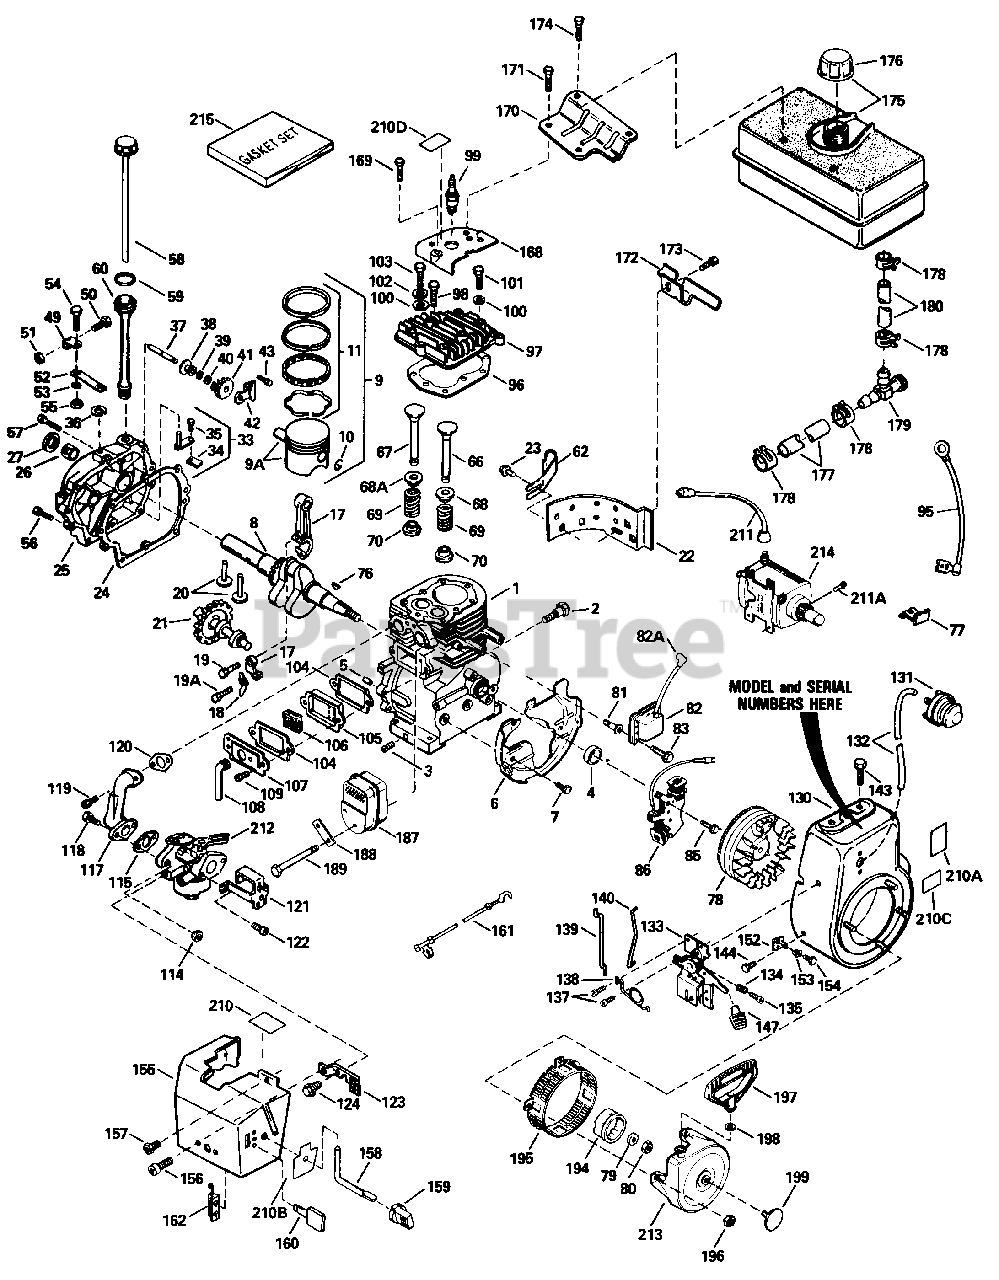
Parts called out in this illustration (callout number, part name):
1	Cylinder
2	Screw, Hex Hd. Shoulder, 1/4-20 x1/2
3	Plug, Pipe
4	Seal, Oil
5	Pin, Dowel
6	Baffle, Blower Housing
7	Screw, Hex Washer Hd. Durlok, 1/420 x 5/8
8	Crankshaft
9	Piston, Pin & Ring Ass'y. (Std.)
9A	Piston & Pin Ass'y. (Std.)
10	Ring Piston Pin Retaining
11	Ring Set, Piston (Std.)
17	Rod Ass'y., Connecting
18	Dipper, Oil
19	Bolt, Connecting Rod
19A	Bolt, Connecting Rod
20	Lifter, Valve
21	Camshaft (Mechanical Compression Release)
22	Extension, Blower Housing
23	Screw, Hex Hd. Sems, 10-24 x 1/2
24	Gasket, Cylinder Cover
25	Cover Ass'y. Cylinder
26	Bushing, Crankshaft
27	Seal, Oil
33	Rod Ass'y., Governor
34	Yoke, Governor
35	Screw, Fil. Hd. Sems, 6-40 x 5/16
36	Ring, Retaining
37	Shaft, Governor
38	Spool, Governor
39	Washer, Flat
40	Ring, Retaining
41	Gear, Governor
42	Bracket, Governor Gear
43	Screw, Hex Washer Hd. Thread Forming, 10-24 x 1/2
49	Clamp, Governor Lever
50	Screw, Hex Washer Hd., 10-32 x 3/4
51	Lock Nut, Hex "Keps," 10-32
52	Lever, Governor
53	Washer, E.T. Lock
54	Screw, Hex Washer Hd., 8-32 x 5/16
55	Lock Nut, Hex "Keps," 8-32
56	Screw, Hex Washer Hd. Powerlok, 1/4-20 x 1-11/16
57	Screw, Hex Washer Hd. Powerlok, 1/4-20 x 1-3/16
58	Dipstick Oil
60	Tube, Oil Fill
62	Clip, Fill Tube
66	Valve Exhaust (Std.)
67	Valve Intake (Std.)
68	Cap Upper Valve Spring
68A	Seal Ass'y., Intake Valve
69	Spring, Valve
70	Cap, Lower Valve Spring
76	Key Flywheel
77	Clip Spring
78	Flywheel (w/Ring Gear)
79	Washer, Lock
80	Nut Flywheel
81	Stud, Solid State Mounting
82	Solid,State Ass'y.
82A	Cover, Spark Plug
83	Screw, Hex Hd. Sems, 10-24 x 1
85	Screw, Hex Hd. Sems, 1/4-20 x 3/4
86	Coil Ass'y., Alternator (18 Watt)
95	Wire, Ground
96	Gasket, Cylinder Head
97	Head, Cylinder
98	Screw, Hex Flange Hd., 5/16-18 x1-1/2
99	Spark Plug
100	Washer, Flat
101	Screw, Special Hex Hd. Tapped, 5/16-18 x 1-3/4
102	Washer, Belleville
103	Screw, Hex Flanged Hd., 5/16-18 x 2
104	Gasket, Breather
105	Body, Breather
106	Element Breather
107	Cover, Breather
108	Tube Breather
109	Screw, Hex Hd. Sems, 10-24 x 1/2
114	Nut & Lock Washer, 1/4-28
115	Gasket, Carburetor
117	Pipe, Intake
118	Screw, Fil. Hd. Sems, 1/4-28 x 1
119	Screw, Torx Fil. Hd. Sems, 5/16-18 x 1-1/8
120	Gasket, Intake Pipe
121	Bracket, Choke
122	Screw Fil. Hd. Sems, 10-32 x 1/2
123	Bracket, Carburetor 0 Cover Mounting
124	Screw, Hex Washer Hd. Sems, Taptite, 8-36 x 5/8
130	Housing, Blower
131	Primer Ass'y.
132	Line Primer
133	Bracket Ass'y., Control
134	Spring Compression
135	Screw, Fil. Hd., 5-40 x 7/16
137	Screw, Hex Washer Hd. Thread Cutting, 10-32 x 1/2
138	Spring, Speed Control
139	Link, Governor
140	Link, Governor-to-Throttle
143	Screw, Hex Hd. Spinlock Thread Forming, 5/16-18 x 3/4
144	Screw, Phil. Hex Hd. Sems, 5/16-24 x 21/32
147	Knob, Control
152	Bracket, Grommet Mounting
153	Grommet, Plastic
154	Screw, Pan Hd. Taptite, 8-32 x 3/8
155	Cover, Carburetor
156	Screw, Hex Washer Hd. Sems, 10-32 x 3/8
157	Screw, Hex Washer Hd. Self- Drilling, 10-32 x 1/2
158	Rod, Choke
159	Knob, Choke
160	Key, Ignition
161	Wire, Ground
162	Terminal Ass'y.
168	Cover, Cylinder Head
169	Screw, Hex Washer Hd. Taptite, 1/4-20 x 5/8
170	Plate, Fuel Tank Mounting
171	Screw, Hex Hd., 5/16-18 x 5/8
172	Bracket, Fuel Tank
173	Screw, Hex Washer Hd. Durlok, 1/4-20 x 5/8
174	Screw, Hex Washer Hd. Thread Cutting, 1/4-15 x 7/8
175	Tank, Fuel
176	Cap, Fuel Tank
177	Line, Fuel
178	Clamp, Fuel Line
179	Valve, Fuel Shut-Off
180	Line, Fuel
188	Plate,Lock
189	Screw, Flanged Hex Hd., 5/16-18 x 4-3/16
194	Hub, Starter
195	Screen, Starter
196	Nut & Lock Washer, 1/4-28
197	Starter Handle, Mitten Grip
198	Washer, Flat
199	Plug, Starter
210	Decal, Instruction
210A	Decal, Name
210B	Decal, Choke
210C	Decal, Primer
210D	Decal, Writing (Bilingual)
211	Cord, Extension
211A	Screw, Hex Washer Hd. Sems, 1/4-20 x 1/2
212	Carburetor
213	Starter, Rewind
214	Motor Kit, Electric Starter (120 Volt)
215	Gasket Set
